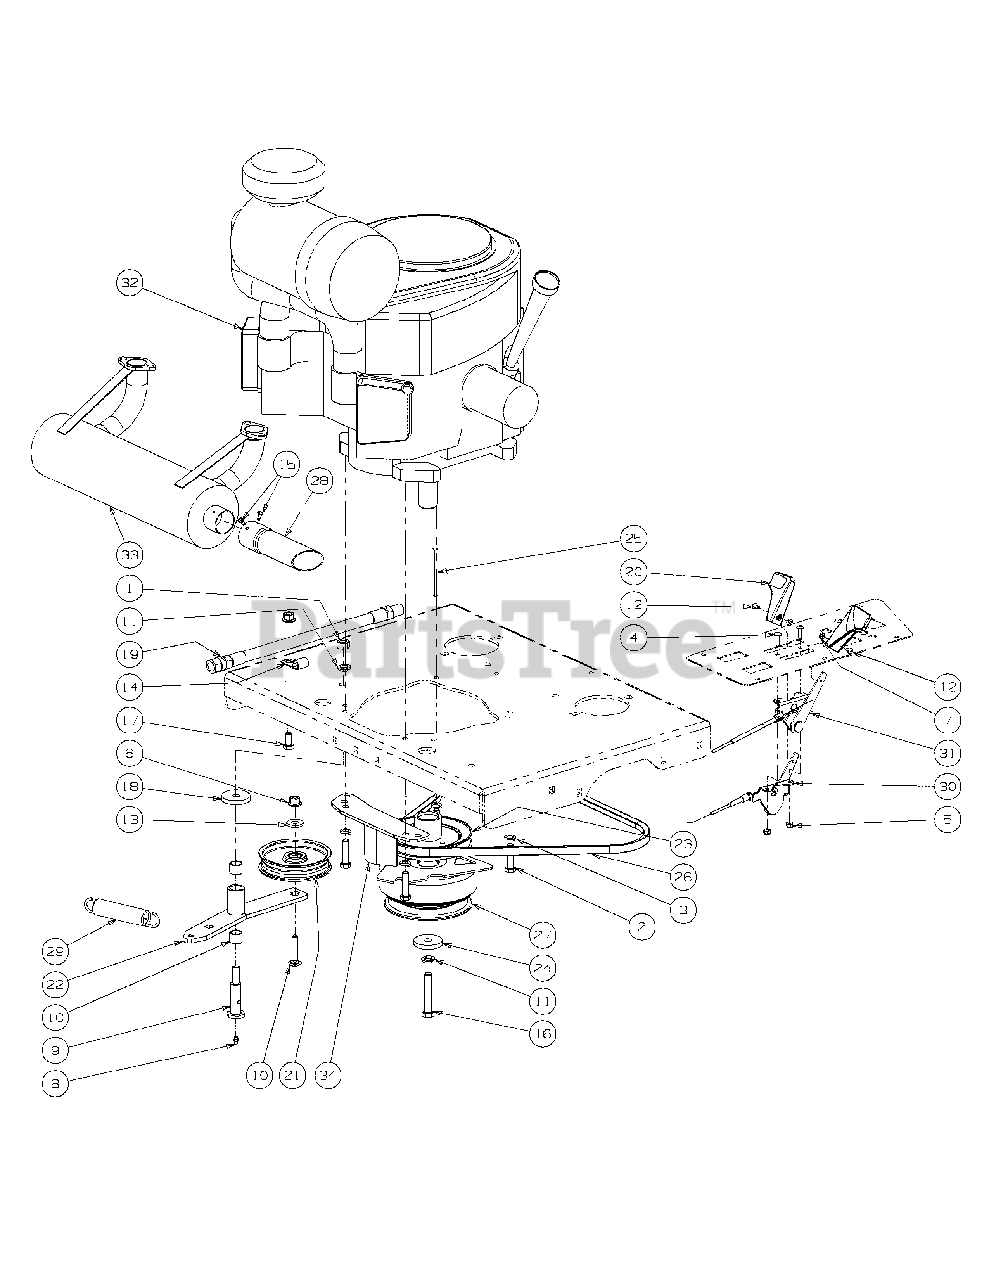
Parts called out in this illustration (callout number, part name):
1	Hex Nut, 7/16-14
2	Hex Head Cap Screw, 3/8-16 x 1.50
3	Washer lock 3/8 zinc
4	Round Hd. Machine Screw, 10-32 x 3/4
5	Lock Nut, Nylon Insert, 10-32
6	Flange Lock, Hex Nut, 3/8-16
7	Nut Washer, W/Star, 8-32
8	Grease Fitting, 1/4-28 x 3/16
9	Shoulder Screw, 7/16-14
10	Hex Carriage Screw, 3/8-16, 1.75
11	Lock Washer, 7/16
12	Machine Screw, 8-32, .375
13	Flat Washer, .406 ID, 1.0 OD, .105
14	Clip, Heat Shield Cable
15	Screw, #8-32 x .375
16	Capscrew, 7/16-20 x 2.50
17	Hex Cap Screw, 3/8-16, .750
18	Flat Washer, 7/16 ID x 1.75 OD x .25
19	Oil Drain Hose
20	Control Throttle Knob
21	Flat Pulley with Flanges
22	Engine Idler Arm
23	Pump Drive Pulley
24	Flat Washer, 7/16 ID x 1.75 OD x .25
25	Key, 1/4 x 1/4 x 3
26	Belt, 51.2 Lg
27	Clutch Brake, 1.125 ID, 5.34 inch pulley
27	Clutch Brake, 1.125 ID, 6.0 inch pulley
28	Muffler Accessory Exhaust Tube
29	Extension Spring, .98 OD x 5.00
30	Throttle, Control Cable
31	Choke, Control Cable
32	Engine, 37HP Kawasaki
33	Muffler, Kawasaki
34	Retainer Clutch Assembly
